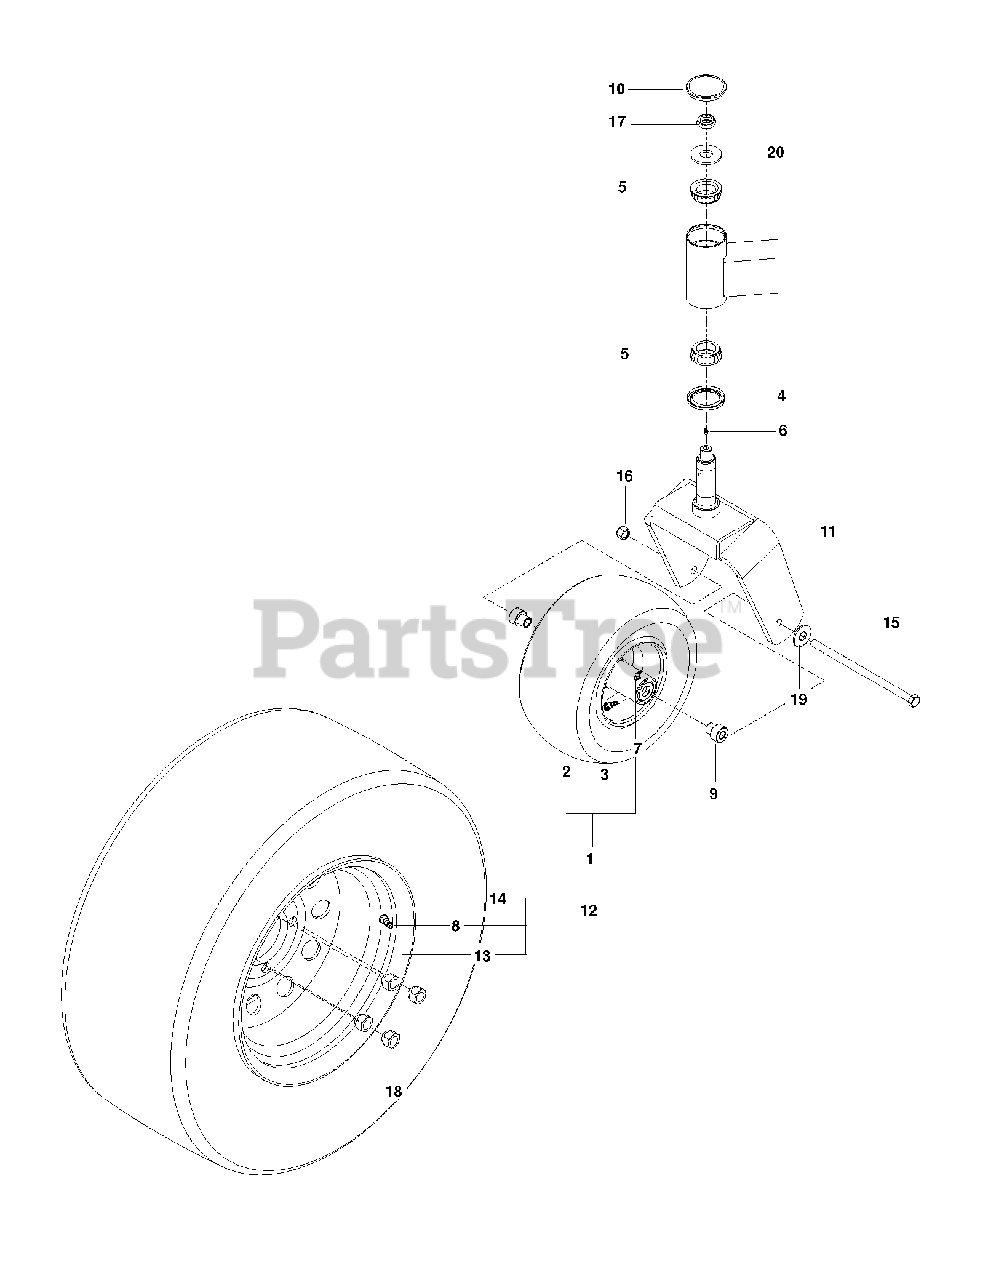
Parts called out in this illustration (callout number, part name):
1	FRONT TIRE ASSY
2	TIRE - SMOOTH 13X6.50-6
4	SEAL, BEARING
5	CONE, LM67048
7	ZERK
8	VALVE STEM TR-412
9	AXLE SPACER
11	FORK.CASTER.ORANGE
12	TIRE 23X8.5-12
13	RIM 12X7 .236 NEG OFFSET
14	TIRE - 23X8.5-12
15	HEX SCREW 1/2-13 X 9.5 GR5
16	NUT, 1/2-13 HEX FLG NYLOC ZD
17	NUT, 3/4-16 HEX THIN NYLOC ZD
18	LUG NUT 1/2F
19	WASHER 1/2" FLAT
20	WASHER, 3/4 HARDENED
